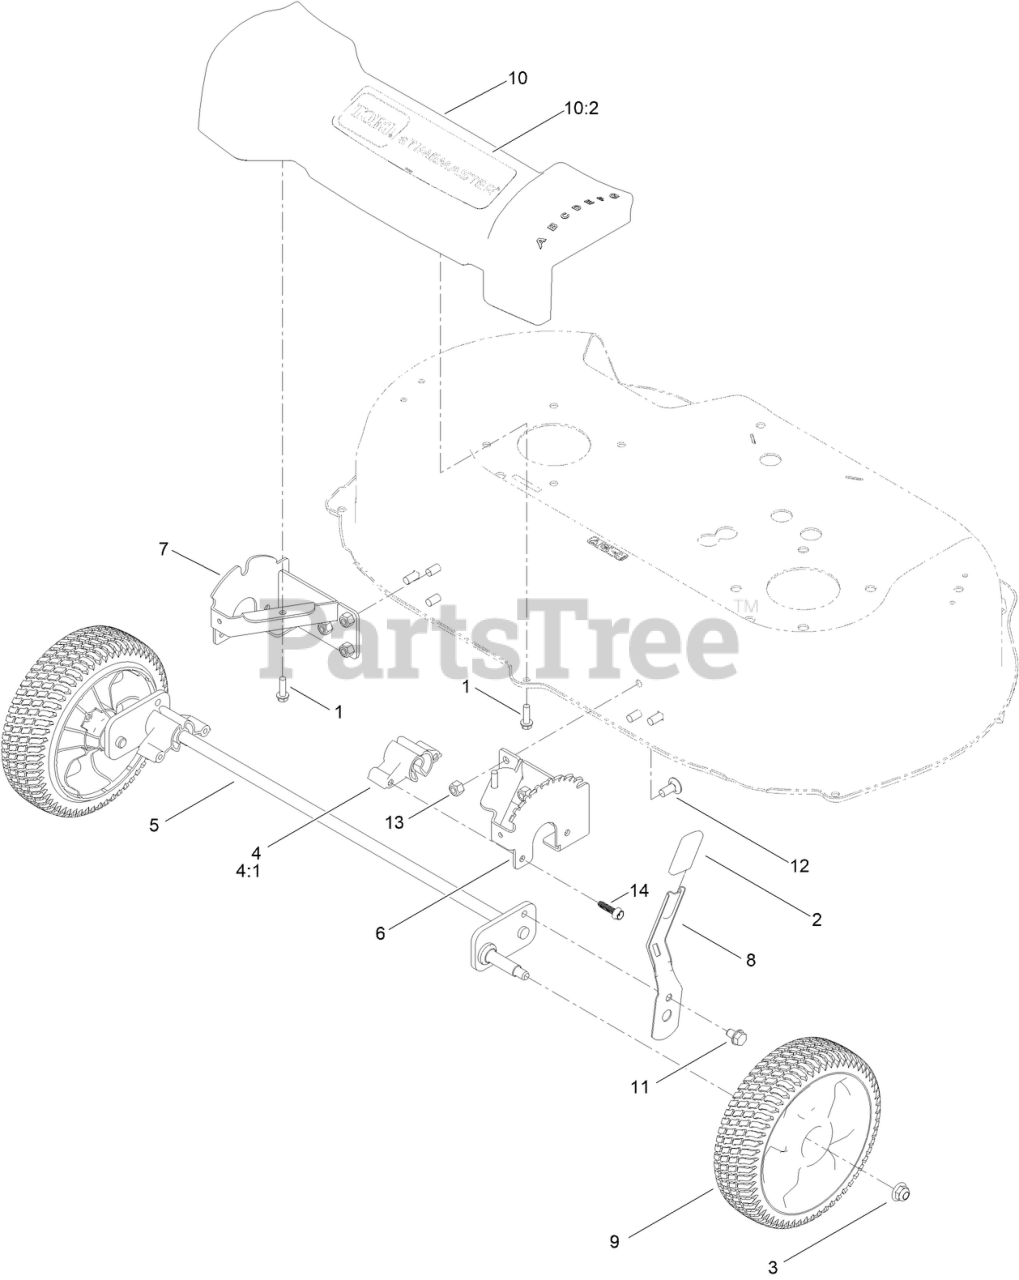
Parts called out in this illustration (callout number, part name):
1	SCREW-HWH
2	GRIP-LEVER
3	NUT-HF, NI
4	BUSHING-PIVOT, FRONT
4:1	RESIN-NYLON 66
5	FRONT AXLE ASM
6	PLATE-HOC, LH
7	PLATE-HOC, RH
8	ARM-SPRING
9	8 INCH WHEEL ASM
10	FRONT COVER ASM
10	Front Cover ASM
10:2	ARTWORK-TORO TIMEMASTER
11	SCREW-HWH
12	SCREW-CARR
13	NUT-LOCK, NI
14	SCREW-FLANGE, PLASTIC
